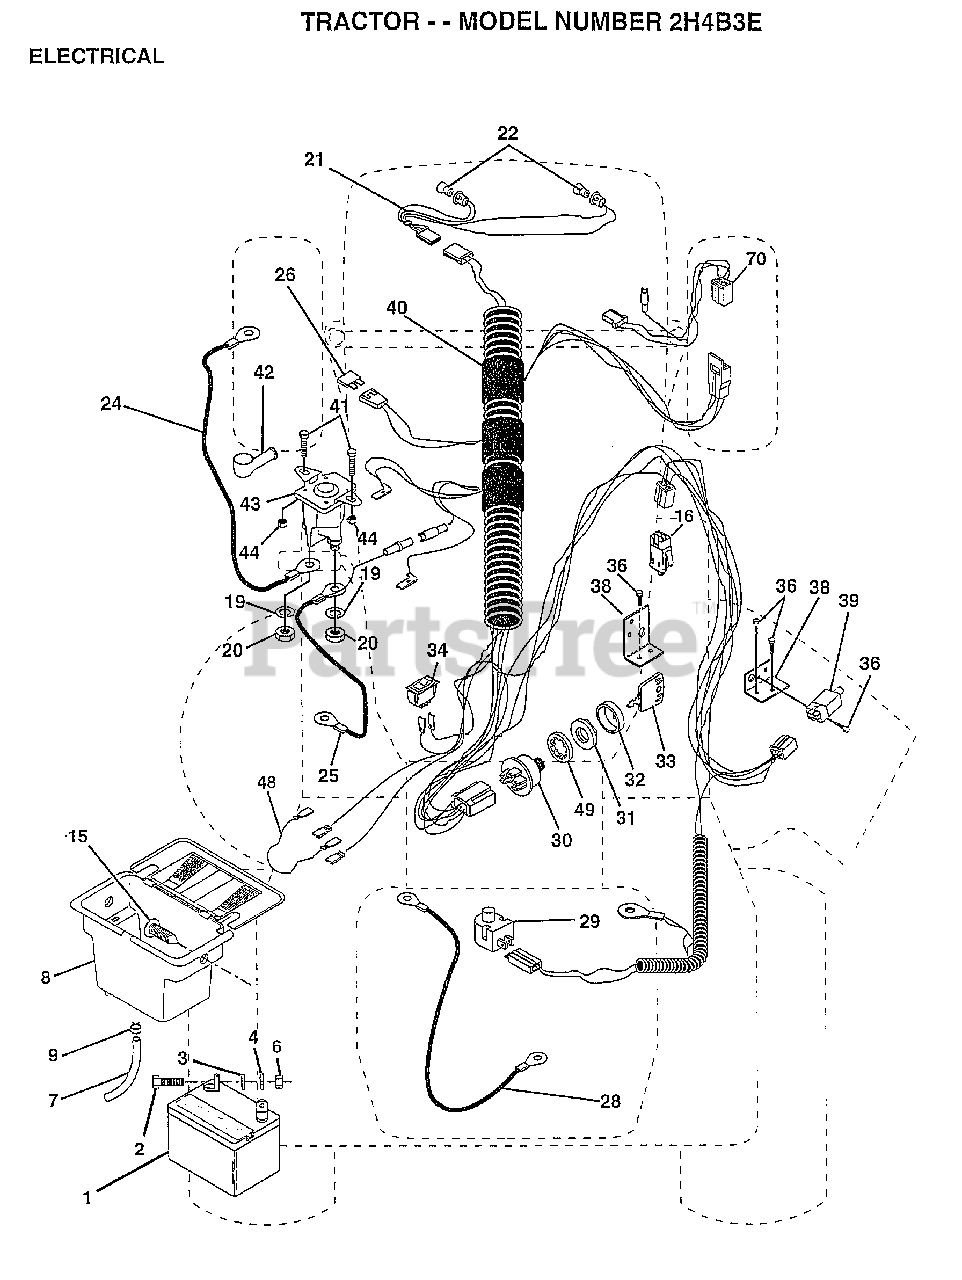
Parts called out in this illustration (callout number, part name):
3	WASHER
4	LOCKWASHER
7	TUBE T
9	HOSE CLAMP T
15	FASTNER.SNAP-IN
16	SWITCH INTERLOCK
20	NUT
21	"HARNESS,LIGHT SOC"
22	HEADLAMP BULB
24	"CABLE T, BATTERY"
25	CABLE.BTRY.6GA.RD
26	FUSE HYT
28	CABLE T
29	SWITCH SEAT
32	COVER KEY SWITCH
33	KEY MLD GEN DELTA
34	SWITCH LT
35	BRACKET LT
36	SCREW
39	SWITCH INTERLOCKT
40	HARNESS.IGN.DASH.
41	BOLT HXHD FIN
44	NUT
45	ADAPTER AMMETER
49	WASHER PINNED
70	HARNESS ENG DUAL
